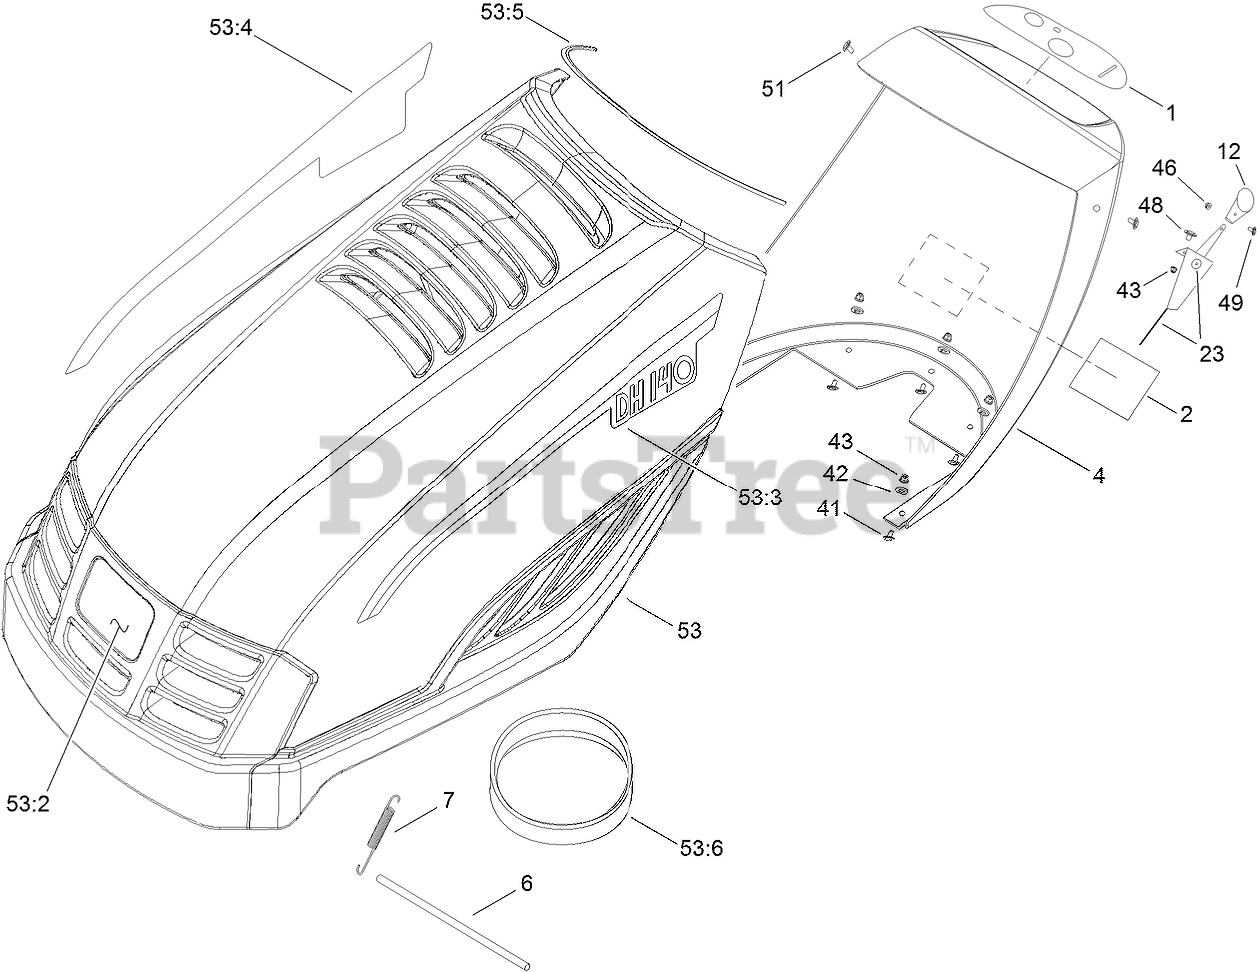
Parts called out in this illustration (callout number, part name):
1	DECAL-PANEL
2	DECAL-INSTRUCTIONS, OPERATING
4	PANEL-DASH
6	BAR-SAFETY
7	SPRING-HOOD
12	KNOB-THROTTLE/CHOKE
23	CABLE-THROTTLE/CHOKE
41	SCREW-HEX
42	WASHER-FLAT
43	NUT-LOCK
46	NUT-HEX
48	SCREW-FLAT HEAD
53	HOOD ASM
53:3	DECAL-DH 140 (LH)
53:4	DECAL-DH 140 (RH)
53:5	RUBBER-PURL
53:6	GASKET-FOAM
